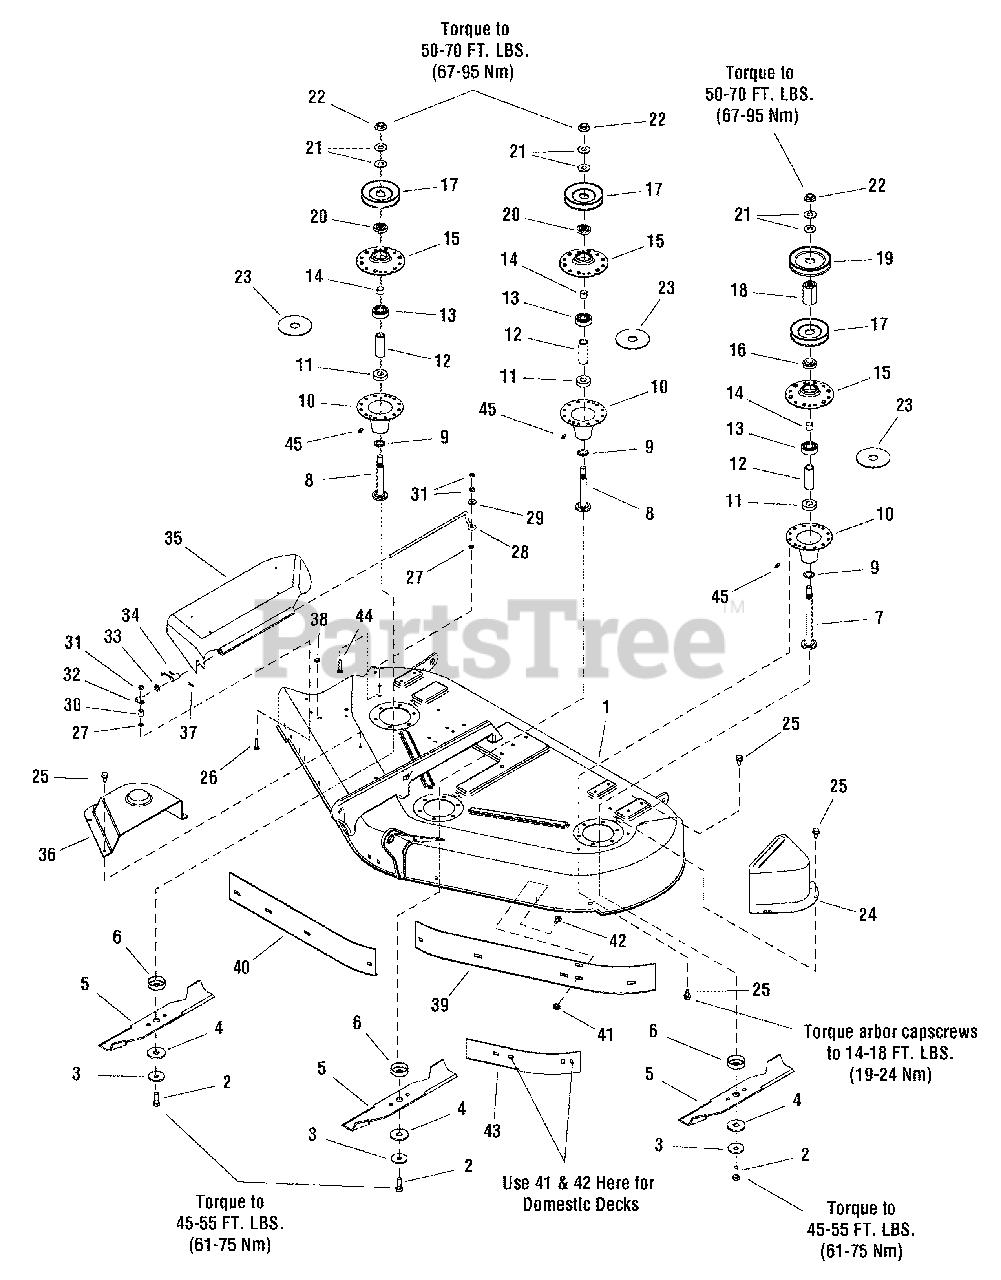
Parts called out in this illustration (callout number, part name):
1	HOUSING ASSEMBLY, 44"
2	CAPSCREW, Hex Head 7/16-14 x 1-1/4 G8
3	WASHER, Spring
4	WASHER, Hex, 11/16 x 2
5	BLADE, Mower
6	SHIELD, Grass Lower Arbor Heat Treat
7	SHAFT, Arbor
8	SHAFT, Arbor
9	WASHER, Cup
10	HOUSING, Arbor Bottom w/Lube Fitting (Includes Ref. No. 45)
11	BEARING, Ball 11/16 x 1-9/16 x 15/32
12	SPACER, Powdered Metal
13	BEARING, Ball
14	SPACER, 21/32 x 3/4 x 5/8
15	HOUSING, Arbor Top
16	HUB, Powdered Metal
17	PULLEY
18	HUB, Hub Serated
19	PULLEY
20	HUB, Pulley, Center & R.H.
21	WASHER, Bellville
22	NUT, Hex Flange 9/16-18
23	GASKET
24	COVER, Arbor
24	COVER, Arbor (No Ribs)
25	SCREW, Hex Washer Head Taptite 5/16-18 x 3/4
26	CARRIAGE BOLT, 1/4-20 x 1-1/2 G5
27	NUT, Push for 1/4 Diameter Thread
28	ROD, Deflector
29	SPACER
30	CARRIAGE BOLT, 1/4-20 x 1-1/4 G5
31	NUT, Hex Lock ESNA Light 1/4-20
32	CLAMP, Wire, 5/16 Diameter
33	WASHER, 5/16
34	SPRING, Torsion Chute
35	DEFLECTOR
36	COVER, Arbor
37	NUT, Hex Flange 5/16-18 Whiz Lock Small
38	PLUG, Button
39	BAFFLE, Blowout 44" LH
40	BAFFLE, Blowout 44" RH
41	NUT, Hex Flange 5/16-18 Whiz Lock Large
42	CAPSCREW, Hex Head 5/16-18 x 1 G5
43	BAFFLE, Short Blowout
44	CARRIAGE BOLT, 1/4-20 x 1-1/2
45	FITTING, Grease 1/4 Drive
